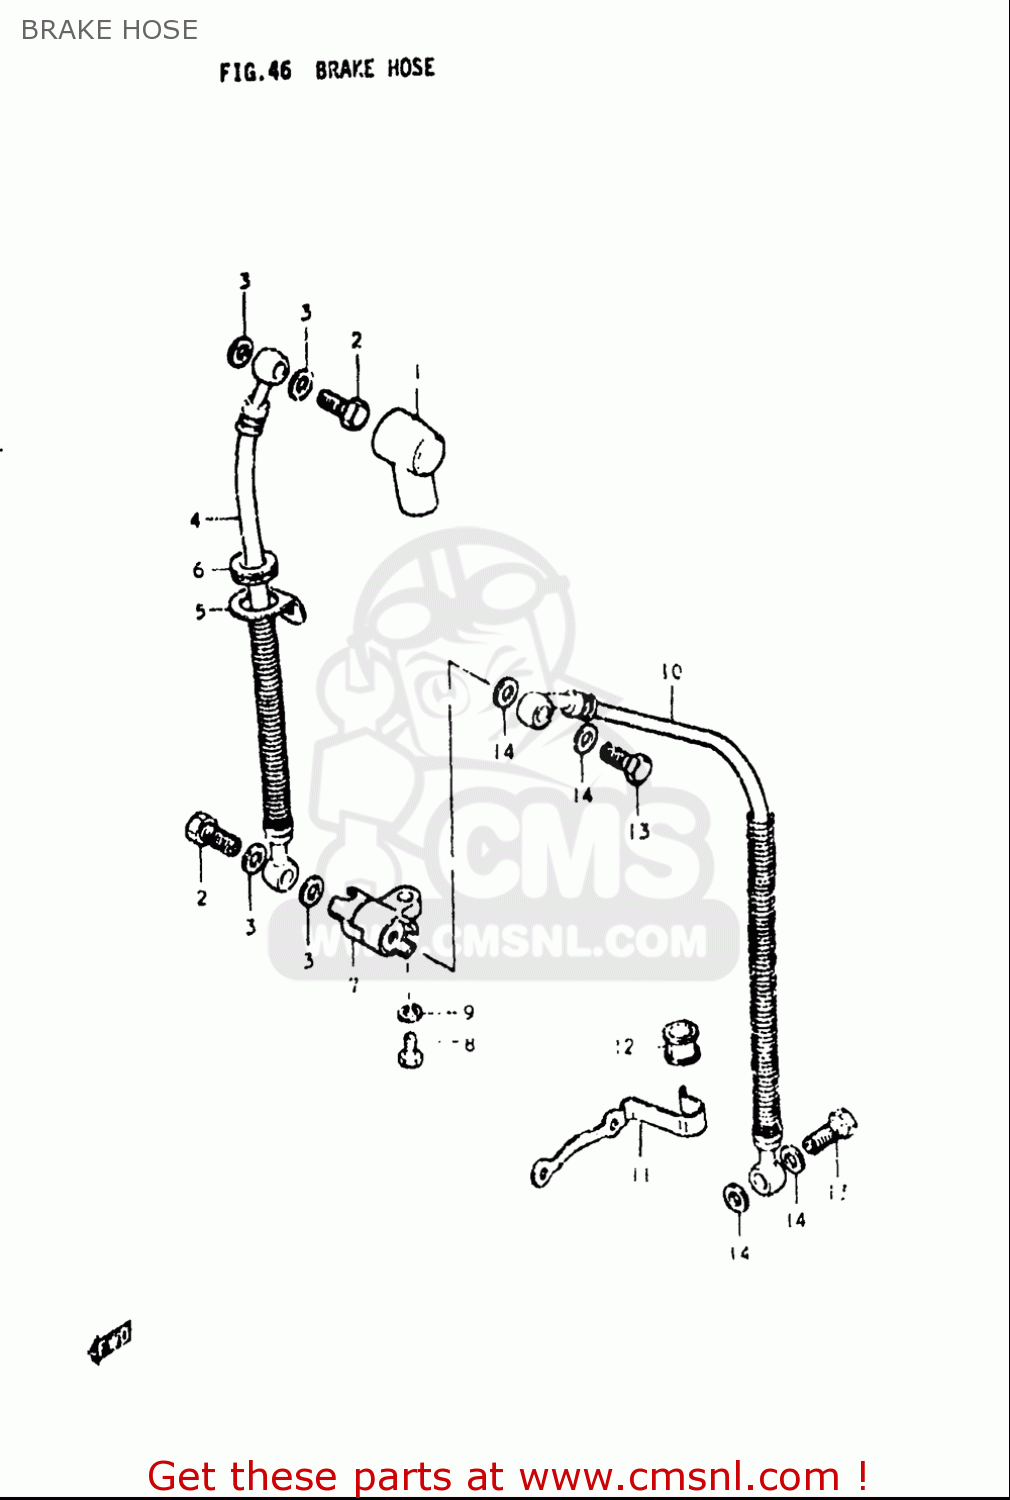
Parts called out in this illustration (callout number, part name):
1	BOOT,MASTER CYLINDER
2	BOLT UNION
3	WASHER(10X15X1.5)
4	HOSE,FRONT BRAKE NO.1
5	GUIDE,BRAKE HOSE
6	GROMMET
7	JOINT,BRAKE HOSE
8	BOLT
9	WASHER,LOCK
10	HOSE,FR BRAKE NO.2,L
11	GUIDE,BRAKE HOSE NO.2
12	BUSH,BRAKE HOSE GUIDE,NO.2
13	BOLT UNION
14	WASHER(10X15X1.5)
